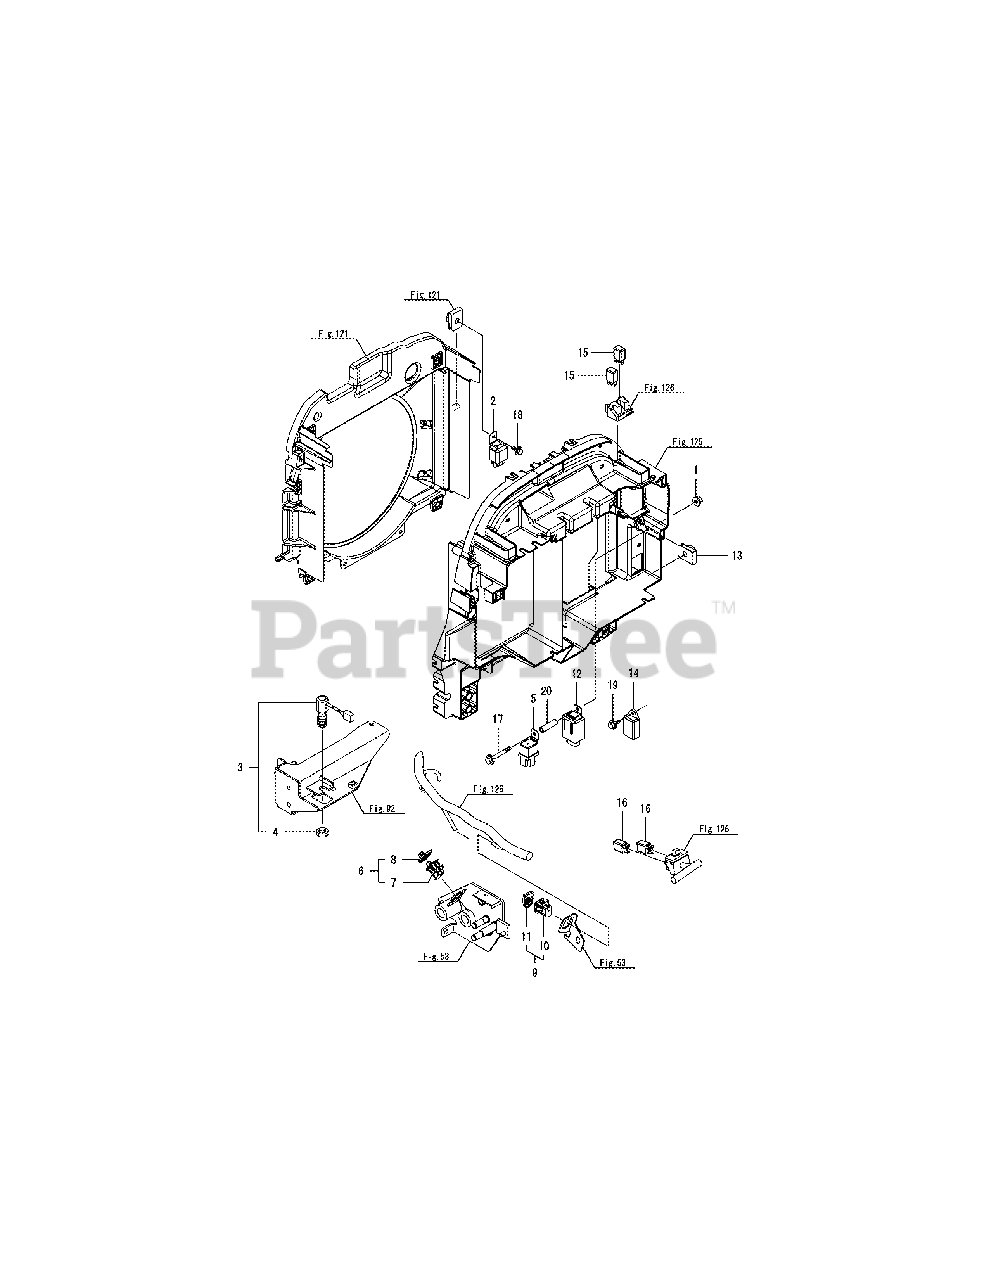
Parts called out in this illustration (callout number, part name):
1	NUT W/WASHER 6
2	RELAY, STARTER
3	SWITCH, BRAKE LAMP
4	LOCK NUT M12 PLATED
6	SWITCH NC ASSY, PEDAL
7	SWITCH NC, PEDAL
8	PROTECTIVE COVER,
9	SWITCH, SEAT, DELTA,AS
10	SWITCH, SEAT, DELTA,AS
11	PROTECTIVE COVER,
15	RELAY(ACM13211M01
16	RELAY(ACM13211M01
17	BOLT M 6X 50 PLATED
18	BOLT M 6X 16 PLATED
19	BOLT M 6X 16 PLATED
